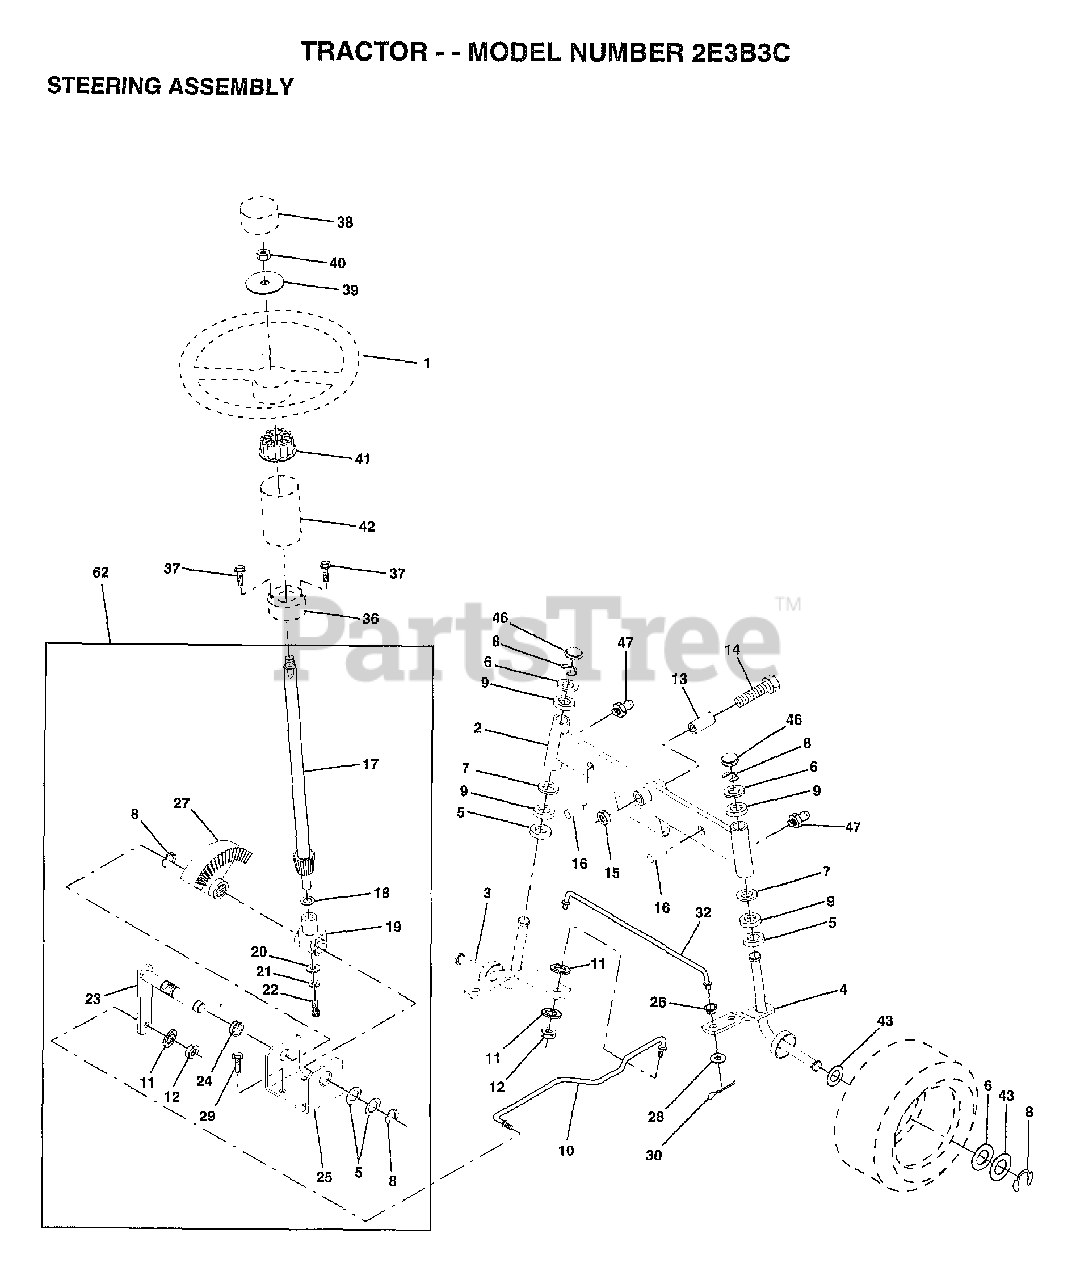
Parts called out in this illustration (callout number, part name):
2	AXLE ASM FRONT
3	SPINDLE LH
4	SPINDLE RH
5	WASHER .T
6	WASHER
7	WASHER
8	RING
9	COL. SRTG. BEAR.
11	LOCKWASHER
13	BEARING
14	BOLT HEX 5/8-11
15	"NUT-LOC,FLANGE LT"
16	AXLE PIN
17	SHAFT ASM
18	THRUST WASHER
19	SUPPORT.SHAFT
21	LOCKWASHER
22	"SCREW,SPECIAL"
24	NYLINER T
25	"BRKT,STEERING"
26	BUSHING.DRAGLINK
27	GEAR SECTOR
28	WASHER
29	SCREW
30	COTTER PIN
32	TIE ROD
38	ST WHL INSERT CAP
39	WASHER T
40	GRIPCO NUT
41	ADAPTER-WHEEL LT
42	"TUBE, STR SHAFT"
43	WASHER
46	CAP
47	ZERK M
